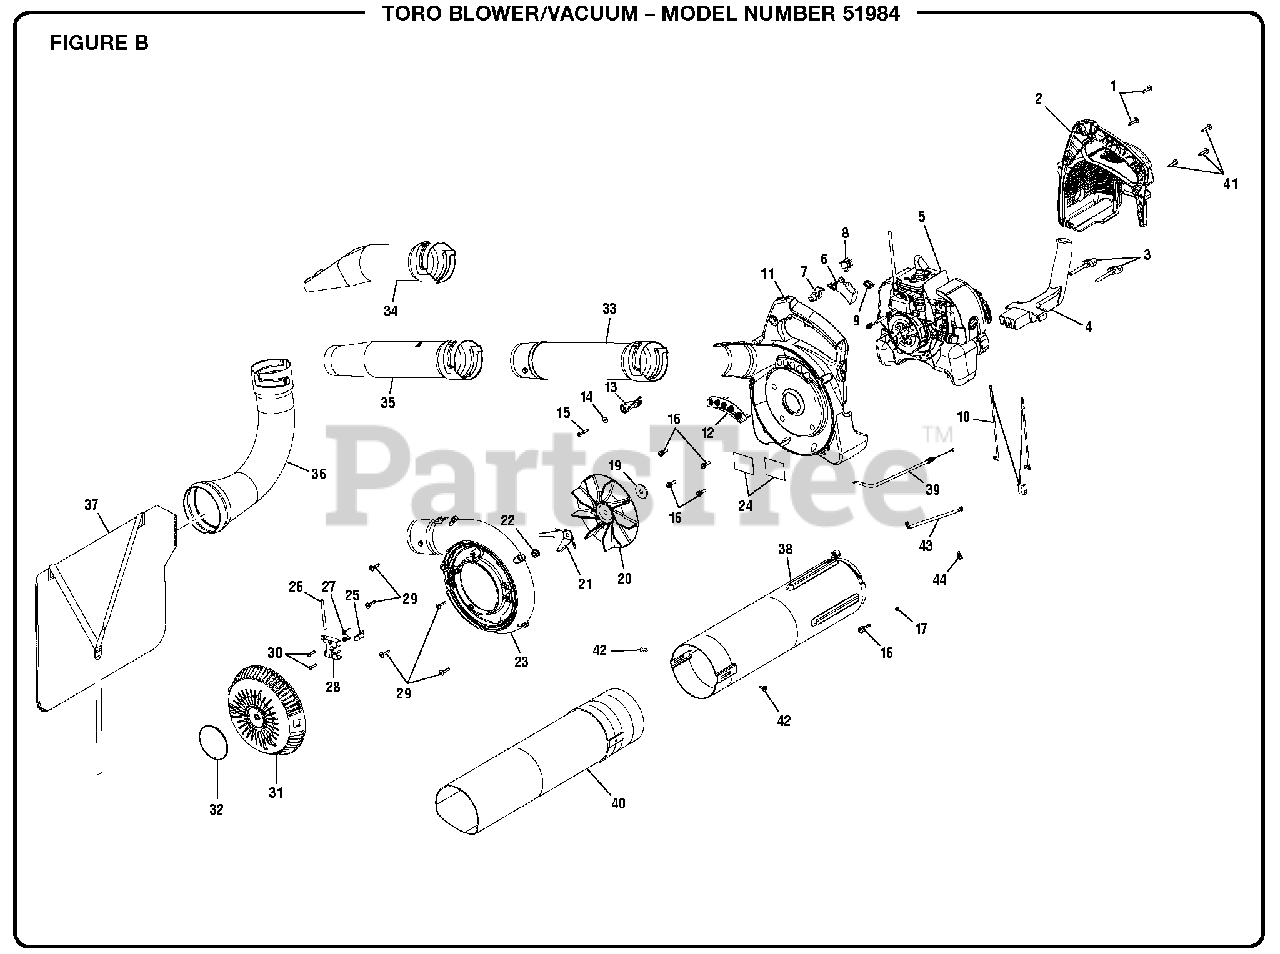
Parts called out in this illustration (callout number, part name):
1	Screw (plastic thd form)
2	Engine Shroud
3	Vacuum Handle Knob
4	Vacuum Handle
6	Throttle Trigger
7	Throttle Lock (Cruise Control)
8	Engine Switch
9	Rubber Grommet
10	Kill Switch
11	Inner Housing
13	Cruise Control Lever
14	Washer (Steel)
15	Screw (Steel)
21	Mulcher Blade
22	Lock Nut (M8 x 1.25)
